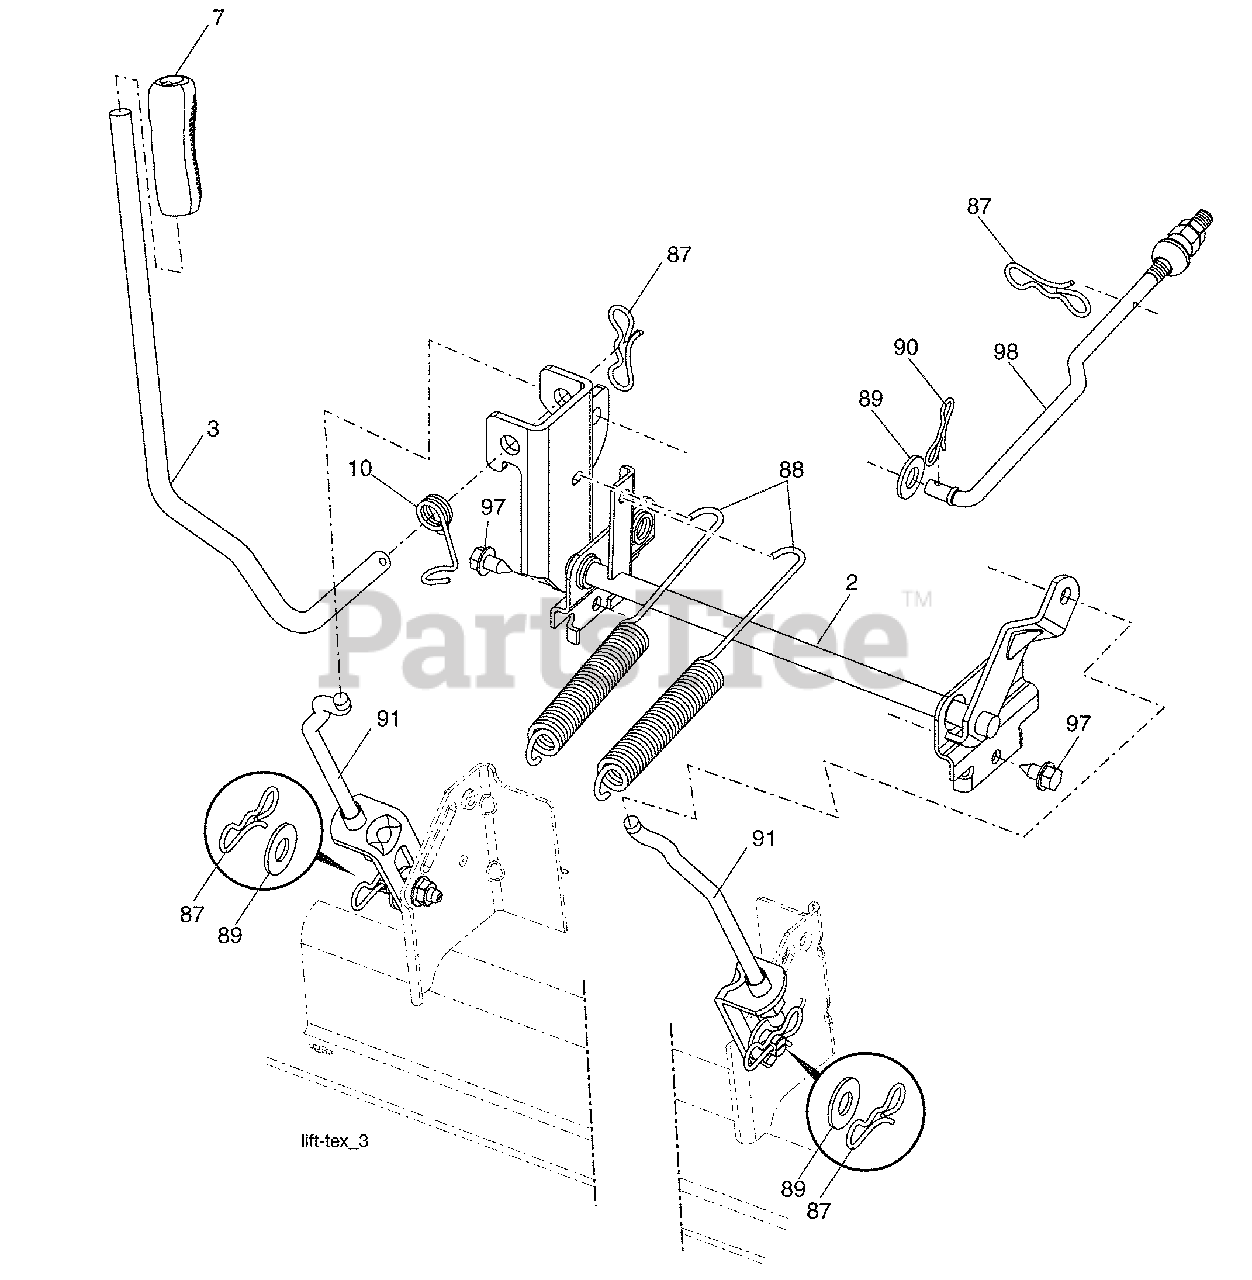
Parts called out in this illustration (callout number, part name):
2	Shaft Asm., Lift
3	Lever Asm., Lift RH
7	Grip, Lever
10	Spring Torsion
87	Pin Cotter 7/16 Bow Tie Lock
88	Spring Lift Assist
89	Washer Clear Zinc
90	Pin Cotter 5/16 Bow Tie Lock
91	Link Lift Susp Mower Rear
97	Screw HEXWSH THDR 3/8-16 x 3/4
98	Link Lift Susp. Front Mower
